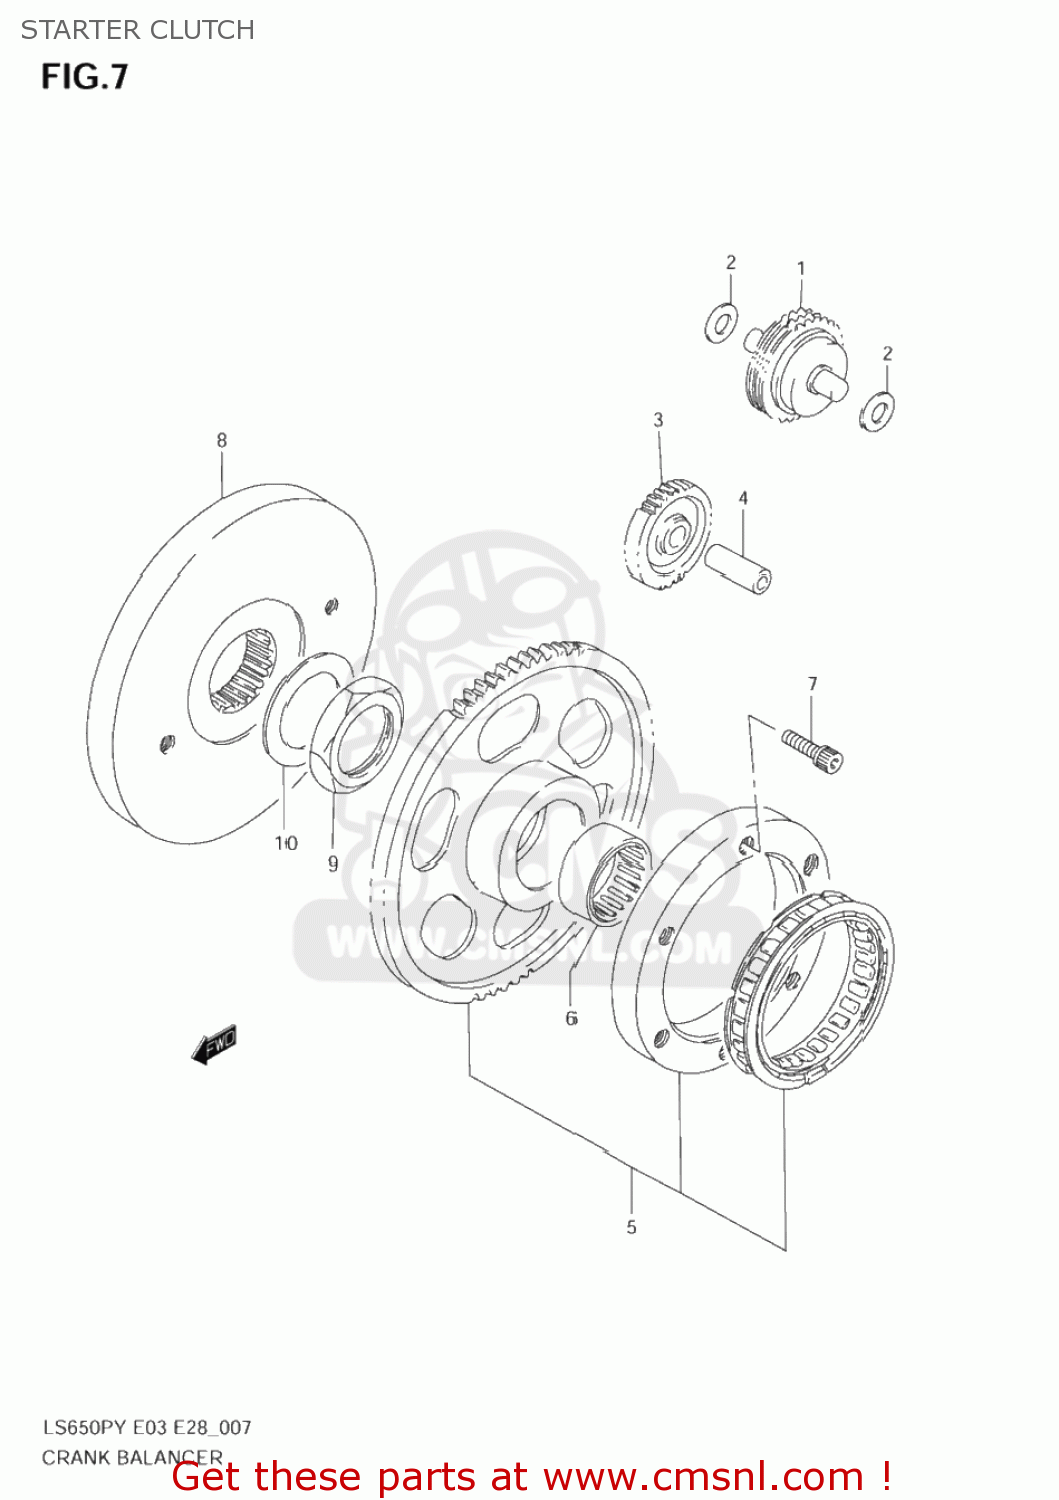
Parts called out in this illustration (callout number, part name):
1	LIMITER ASSEMBLY,STARTER IDLER GEAR
2	WASHER,THRUST
3	GEAR,STARTER IDLE NO.2
4	PIN(10X30)
5	CLUTCH SET,STARTER
6	BEARING(31X39X17.8)
7	BOLT
8	FLYWHEEL
9	NUT,FLYWHEEL
10	WASHER
